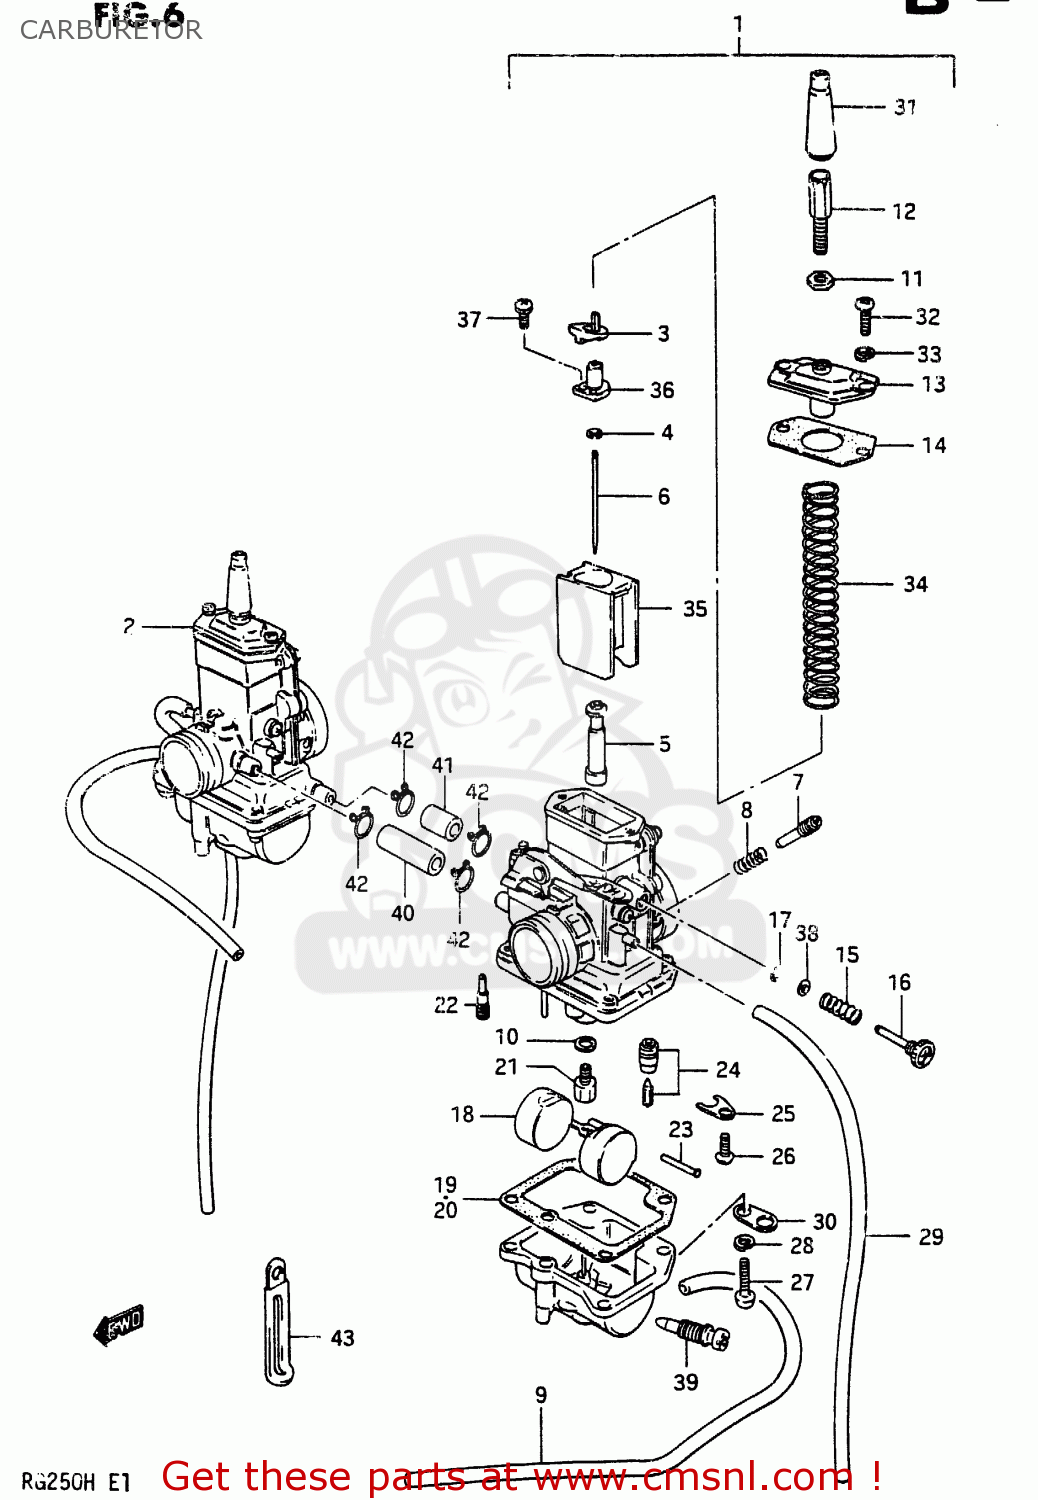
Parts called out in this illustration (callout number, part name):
1	CARBURETOR ASSY,L
2	CARBURETOR ASSY, RH
3	RING
4	CLIP
5	JET,NEEDLE(P-0)
6	NEEDLE,JET
7	SCREW,AIR
8	SPRING
9	HOSE(3X5X650)
10	WASHER,NEEDLE NOZZLE
11	NUT
12	ADJUSTER,CABLE
13	CAP,CARBURETOR TOP
14	GASKET,CARBURETOR TOP (NAS)
15	SPRING
16	ADJUSTER,THROTTLE STOP
17	O RING
18	FLOAT
19	GASKET,FLOAT CHAMBER (NAS)
20	GASKET, FLOAT CHAMBER
21	JET,MAIN(160)
22	JET,PILOT 20
23	PIN,FLOAT
24	VALVE ASSY,NEEDLE
25	PLATE
26	SCREW
27	SCREW
28	WASHER,LOCK 4M
29	HOSE
30	PLATE,CARBURETOR
31	CAP,CABLE ADJUSTER
32	SCREW
33	LOCK WASHER
34	SPRING
35	VALVE, THROTTLE (CA:2.0)
36	JOINT
37	SCREW
38	WASHER
39	PLUG,DRAIN
40	HOSE
41	HOSE
42	CLIP
43	CLAMP
